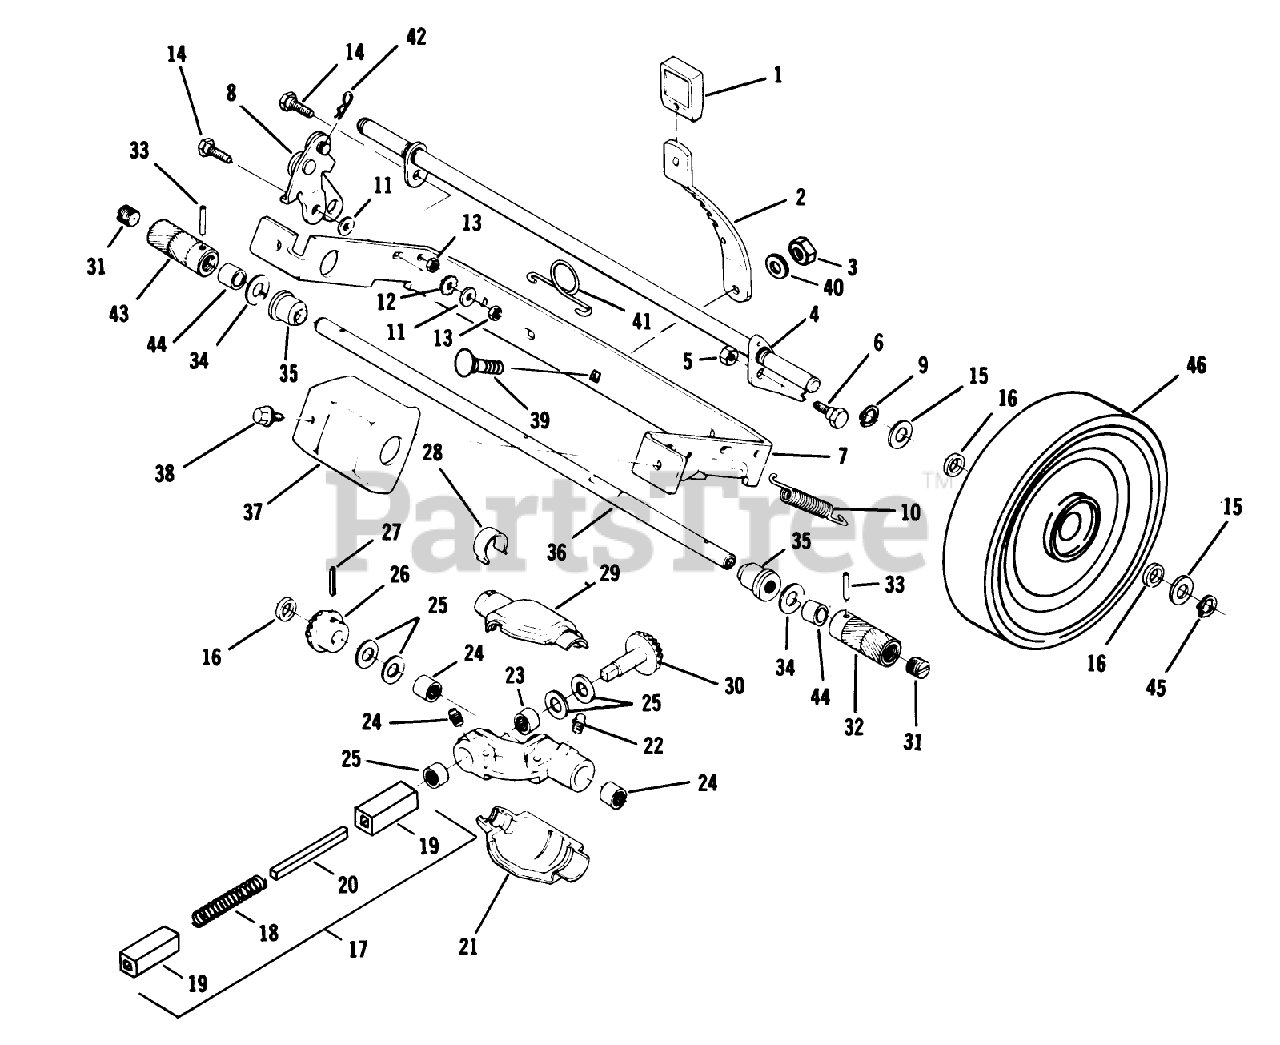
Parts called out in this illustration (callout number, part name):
1	KNOB
2	LEVER
3	LOCKNUT E
4	AXLE & TORQUE LUG ASM
5	LOCKNUT E
6	BOLT RB&W
7	BRACKET *GREEN
9	RET RING
10	SPRING
11	WASHER S
13	STOP NUT
14	BOLT RB&W
15	SPACER
16	WASHER
18	SPRING
19	BUSHING BKWY
22	**FITTING LINCOLN
23	NEEDLE BEARING
25	THRUST WASHER
26	GEAR ADVANCE
27	ROLL PIN
29	GEAR COVER UPPER
30	GEAR BEST
31	GREASE PLUG
32	ROLLER-LEFT
33	PIN
34	Washer
35	SLEEVE &BEARING AY
36	DRIVE SHAFT & TAG
40	WASHER S
41	SPRING N.A.S
43	DRIVE ROLLER
45	RET RING
